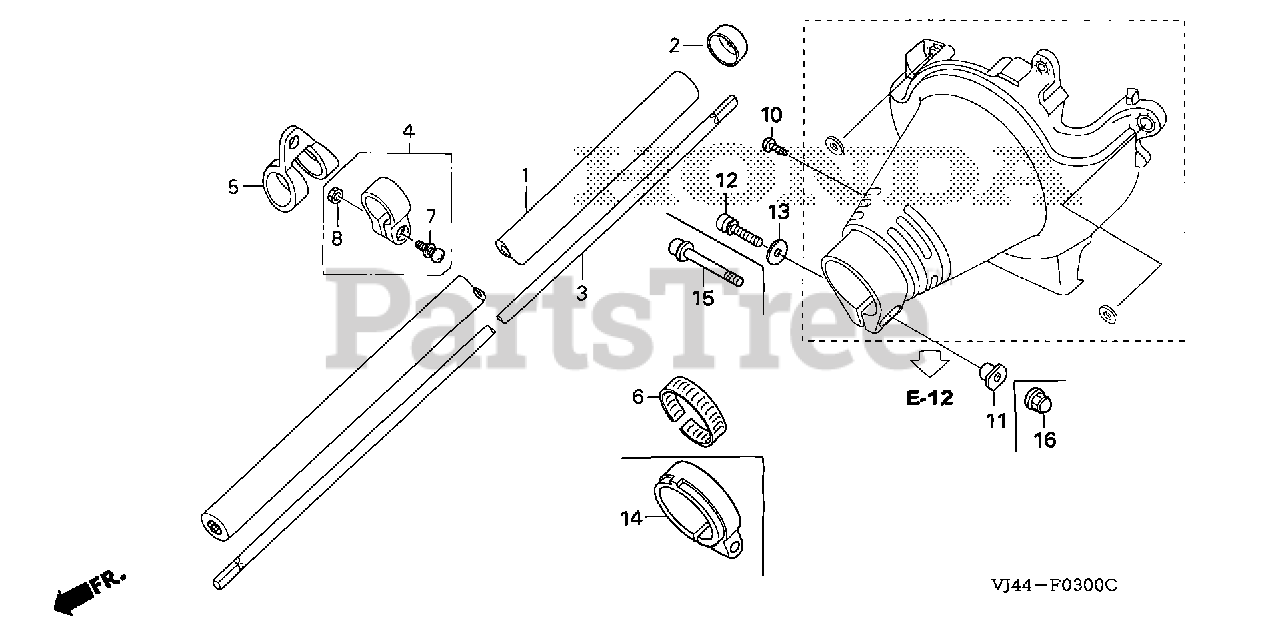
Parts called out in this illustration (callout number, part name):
1	PIPE ASSY., FRAME
2	CAP, FRAME
3	SHAFT, DRIVE
4	HOLDER A, HANGER
5	HOLDER B, HANGER
7	SCREW-WASHER (5X25)
8	NUT, HEX. (5MM)
10	SCREW, TAPPING (5X16)
14	BRACKET, PIPE
15	BOLT, FLANGE SOCKET (5X42)
16	NUT, FLANGE CAP (5MM)
